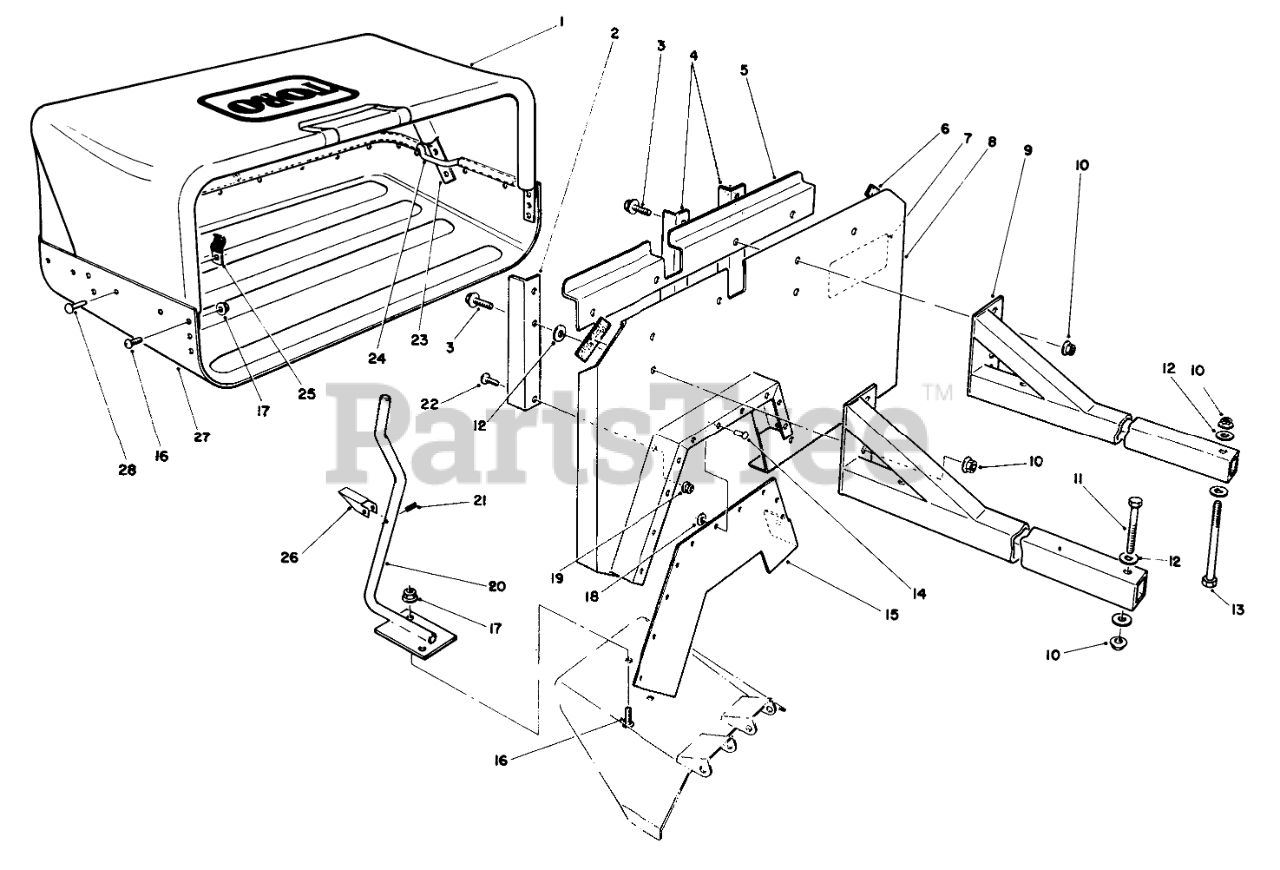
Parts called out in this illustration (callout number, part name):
1	Bag-Cloth
2	Support-Panel, RH
3	SCREW-HHF
4	Support-Panel
5	Support-Bag Attachment
6	PAD-RUBBER
7	DECAL-DANGER
8	Panel-Back
9	Mount-Beam
10	NUT-HHF, WHIZ
11	SCREW-HH
12	WASHER-FLAT
13	SCREW-HH
14	RIVET-POP
15	Extension-Rubber
16	SCREW-PPH
17	NUT-HF
18	WASHER-PLAIN
19	NUT-LOCK, HHF
20	Rod-Lockup
21	PIN-SPRING
23	Tube-Bag Support
24	Rod-Cloth
25	CLIP-HALF
26	LATCH-LOCKUP
27	TRAY-BAG, GRASS
28	RIVET-BLIND
